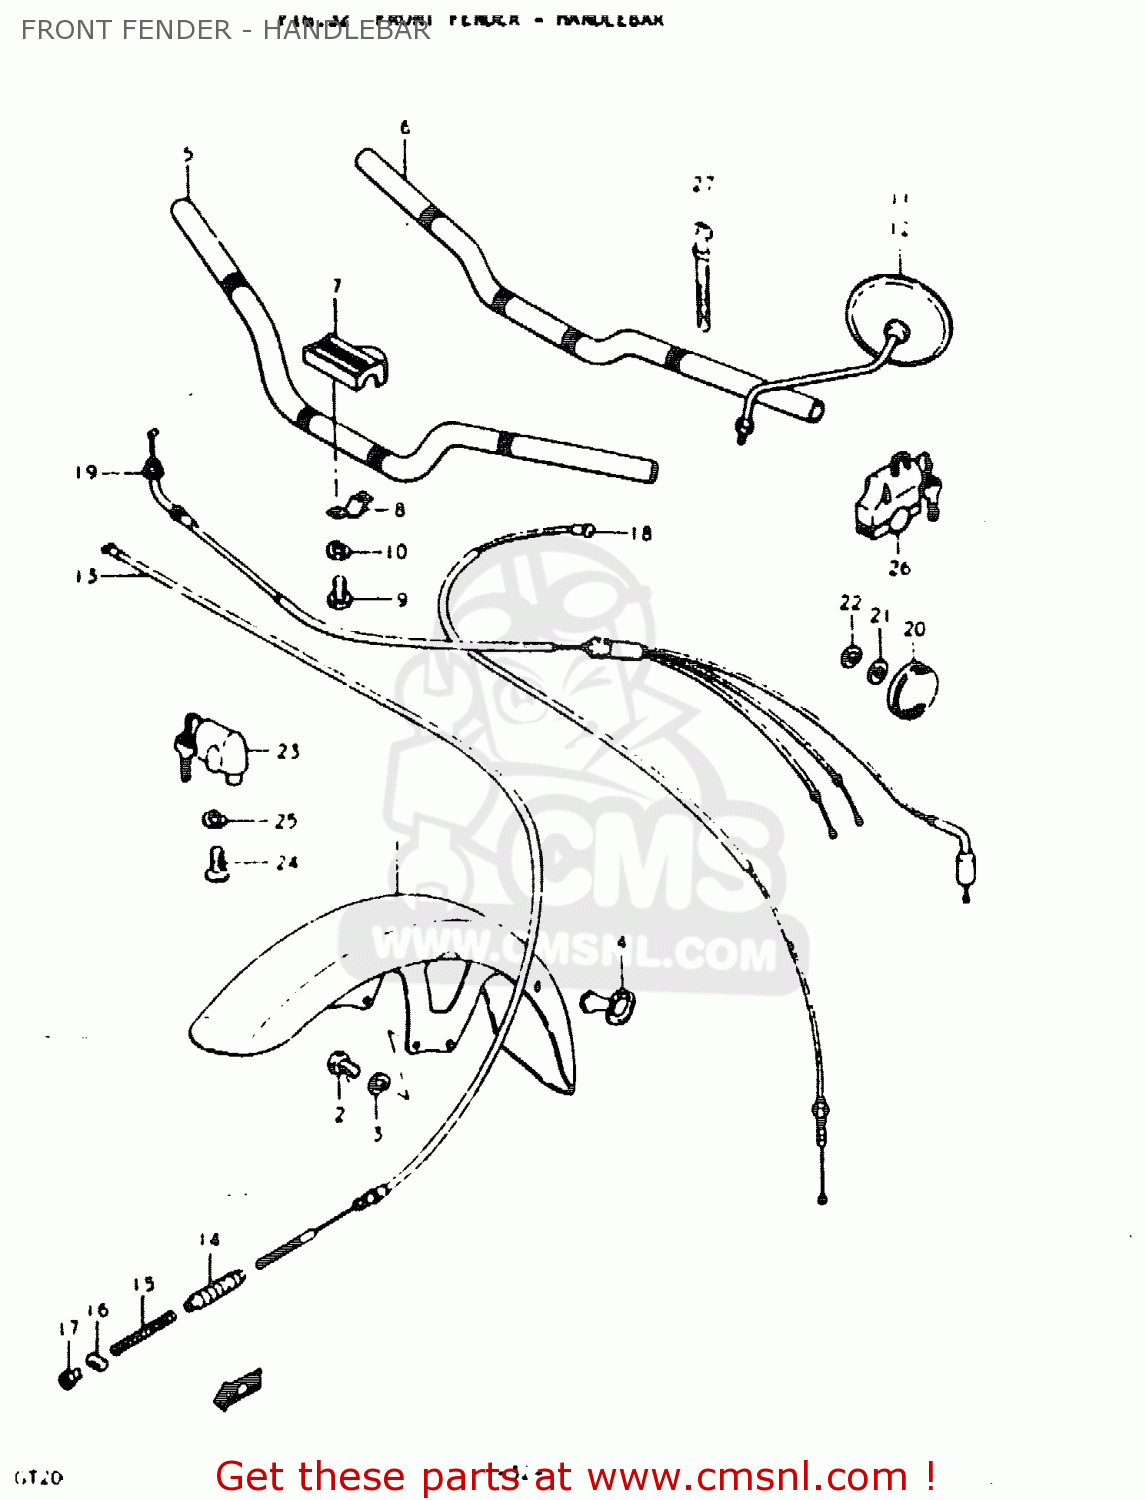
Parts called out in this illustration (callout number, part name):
1	FENDER, FRONT
2	BOLT
3	LOCK WASHER
4	GUIDE,CABLE
5	HANDLEBAR
6	HANDLEBAR
7	COVER, STEERING HEAD
8	BRACKET
9	SCREW
10	LOCK WASHER
11	MIRROR ASSEMBLY,RIGHT
12	MIRROR ASSEMBLY,LEFT
18	CABLE, CLUTCH
19	CABLE, THROTTLE
20	REFLEX REFLECTOR,FR
21	WASHER
22	LOCK WASHER
23	LOCK ASSEMBLY,STEERING
24	SCREW
25	LOCK WASHER
26	LOCK ASSY, HELMET
27	CLAMP(L:120)
